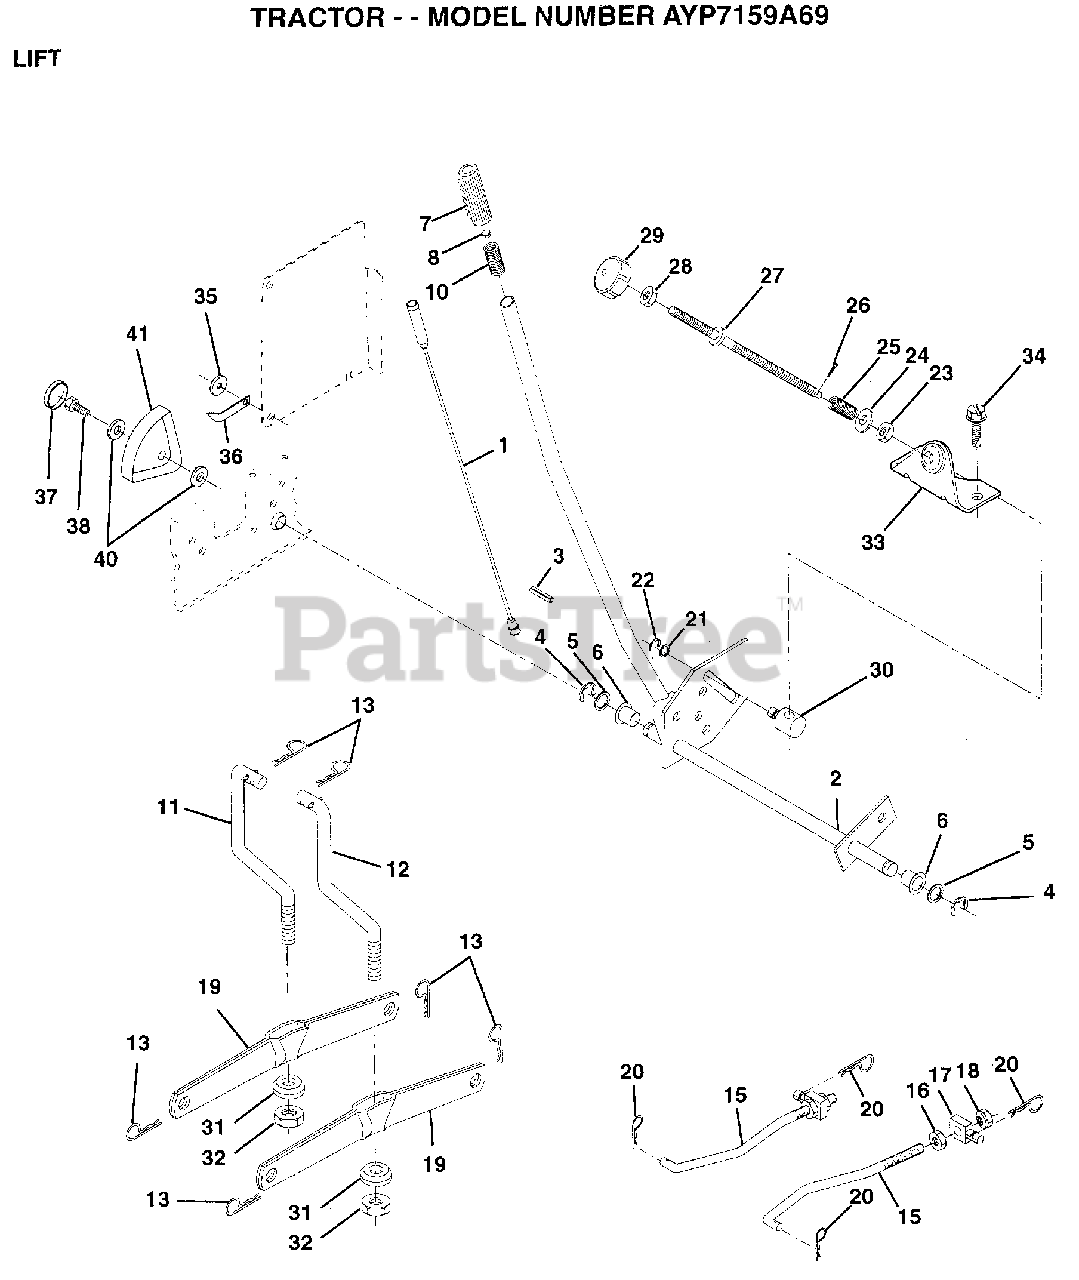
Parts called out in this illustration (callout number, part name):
1	WIRE ASM
2	HANDLE.LIFT.LH.
3	PIN GROOVE
5	WASHER
6	NYLON BEARING
7	GRIP HANDLE
15	LINK.FRONT
16	NUT
17	TRUNION
18	NUT.LK.W/WSH.1/2.
19	ARM SUSP REAR
20	RETAINER.SPRING
21	WASHER
22	KLIP RING
23	NUT T
24	WASHER
25	SPRING T
28	NUT
29	KNOB INF 3/8-16
30	TRUNION LT
31	BEARING PVT LH
32	NUT.CROWNLOCK.3/8
33	BRACKET STOP INF
34	SCREW LT
35	WASHER T
36	POINTER HGT IND
37	"PLUG,HOLE"
38	SCREW
40	WASHER
41	HEIGHT INDICATOR
